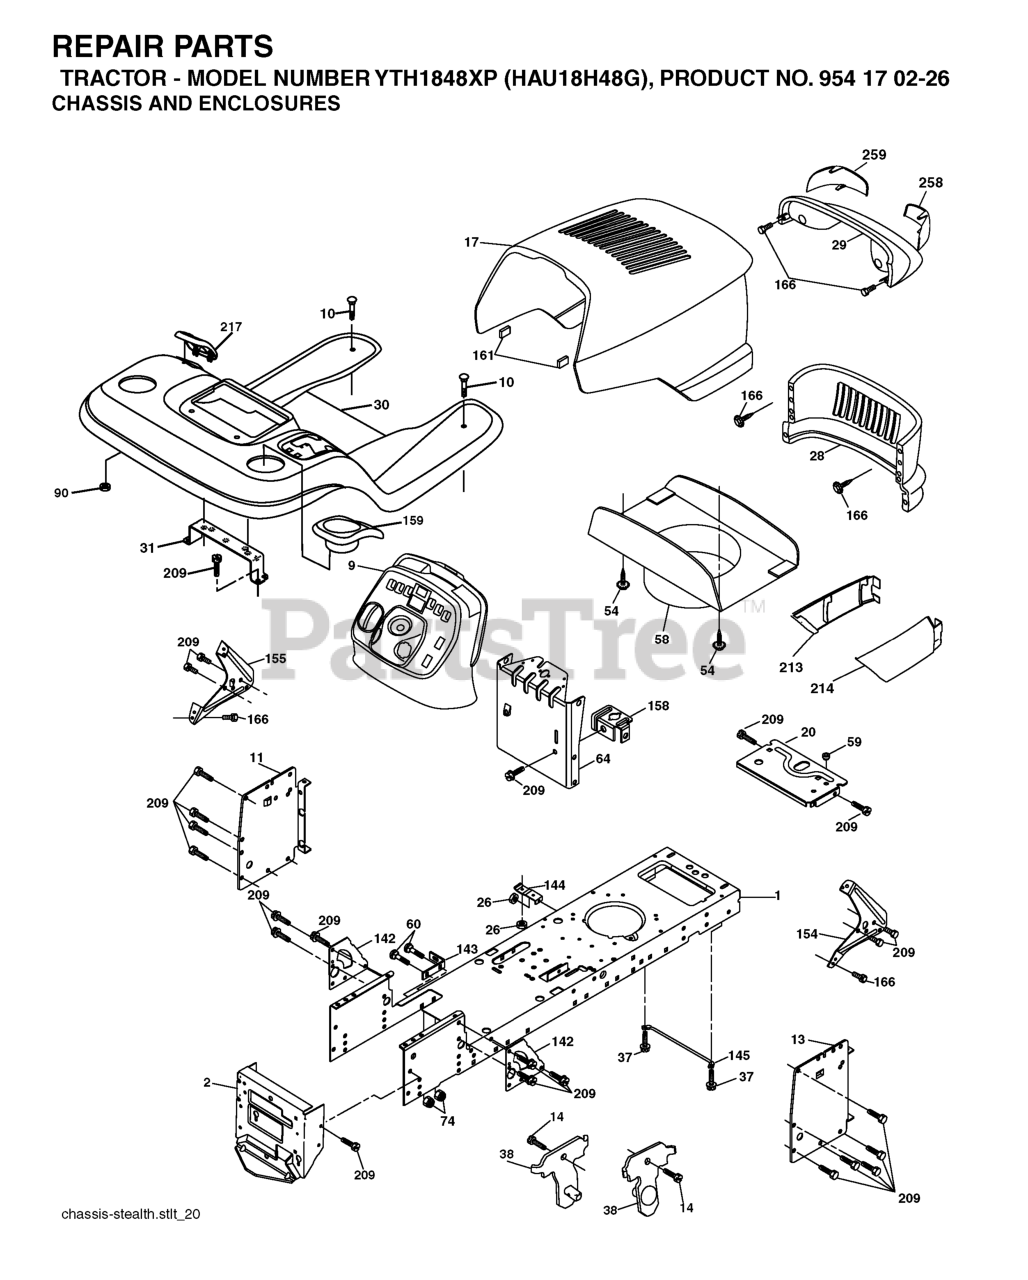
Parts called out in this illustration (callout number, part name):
1	CHASSIS STAMPING
2	DRAWBAR, 12GA
9	DASH, PLASTIC
10	BOLT D
11	PANEL DASH LH
13	PANEL DASH RH
17	HOOD
20	PLATE BATTERY
26	NUT
28	GRILLE.STEALTH P/L.YTGT.GREY
29	LIGHTBOX.ASM.STV.DL.INC.HUSQ
30	FENDER
31	BRACKET.SUPPORT.FENDER
37	Screw 5/16-18 x 1/2 Hex, Self Tapping 5/16-18 x 1/2
38	BRACKET.ASM.PIVOT.MOWER.REAR
54	SCREW.HEX.WS.HD.8-18 X 7/8
59	BUSHING.1.375OD
60	Bolt - Rd. Hd. Sq. Neckiage 3/8 16 x 3/4
64	DASH LOWER
90	NUT.PUSH.3/16
142	PLATE REINFORCEMENT
143	BRACKET, SWAYBAR CHASSIS
144	BRKT, FOOT REST
145	ROD PIVOT CHASSIS/HOOD
154	BRACKET DASH STEALTH(R)
155	BRACKET DASH STEALTH LH
158	BRACKET PARKING BRAKE
159	GREY CUP HOLDER
161	EXTRUSION BUMPER (3 2) (2 2)
166	SCREW
209	SCREW, 3/8-16X3/4
213	SKIRT GRILLE LH
217	CONSOLE FUEL WINDOW
258	LENS RH
259	LENS LH
